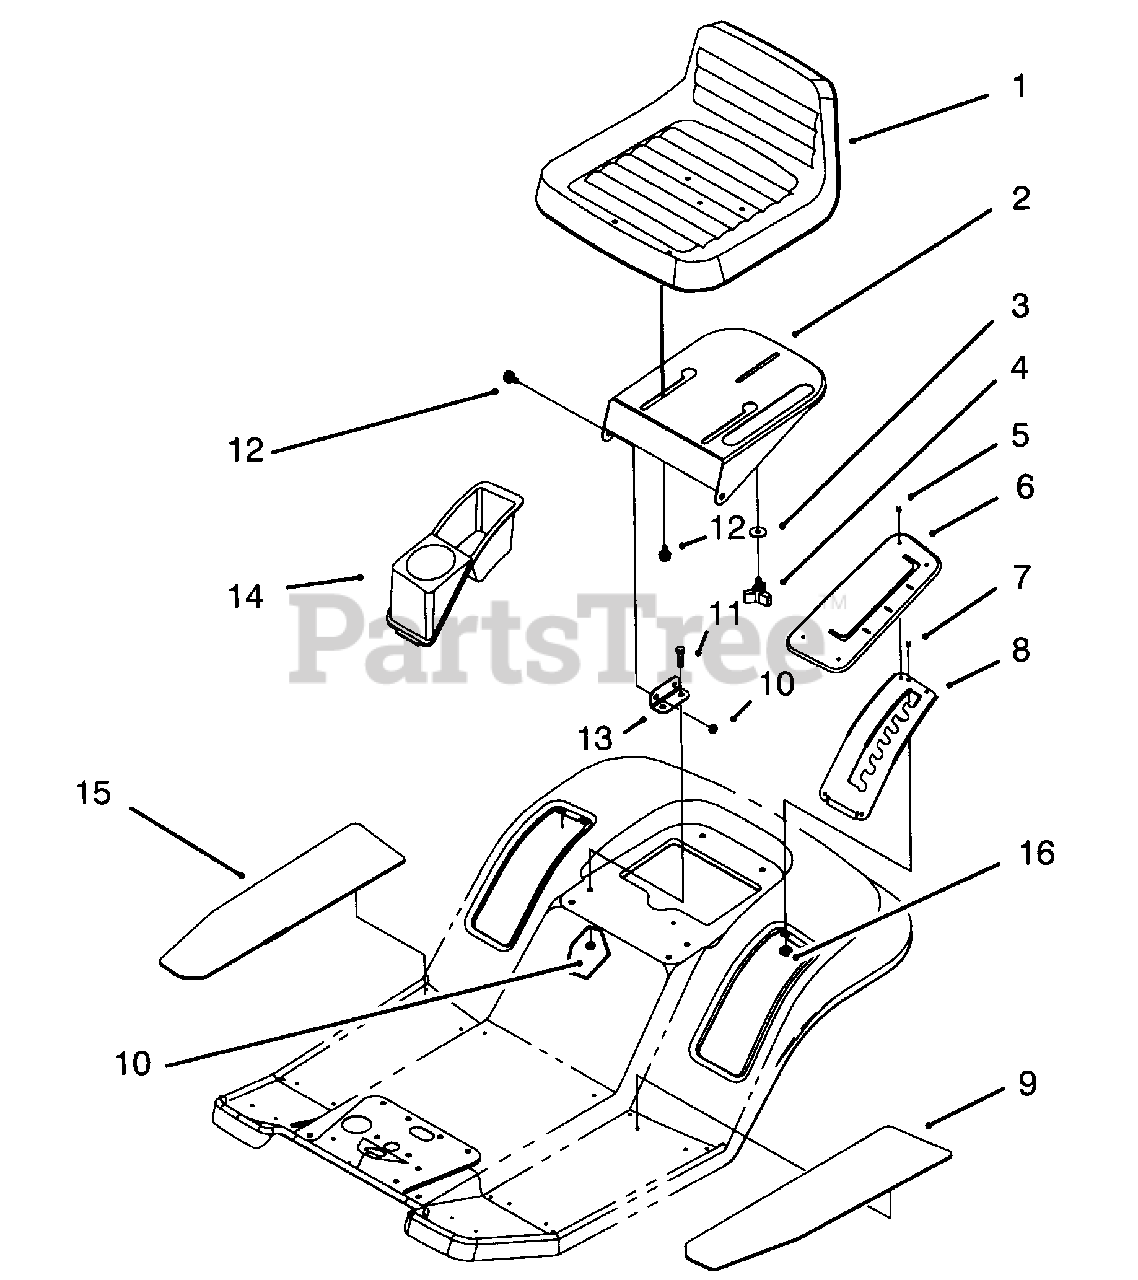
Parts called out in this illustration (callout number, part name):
1	Seat
2	Support-Seat
3	Washer-Fender
4	Knob-Studded
5	Panel-Fastener
6	Cover-H.O.C.
7	Rivet-Pop
8	Gate-H.O.C.
9	Tread-L.H. Foot
10	Nut-Lock
11	Screw-Hex Hd. Cap
12	Bolt-Shoulder
13	Bracket-Seat Hinge
14	Tray-Fender
15	Tread-R.H. Foot Hydro
16	Washer-Backup
